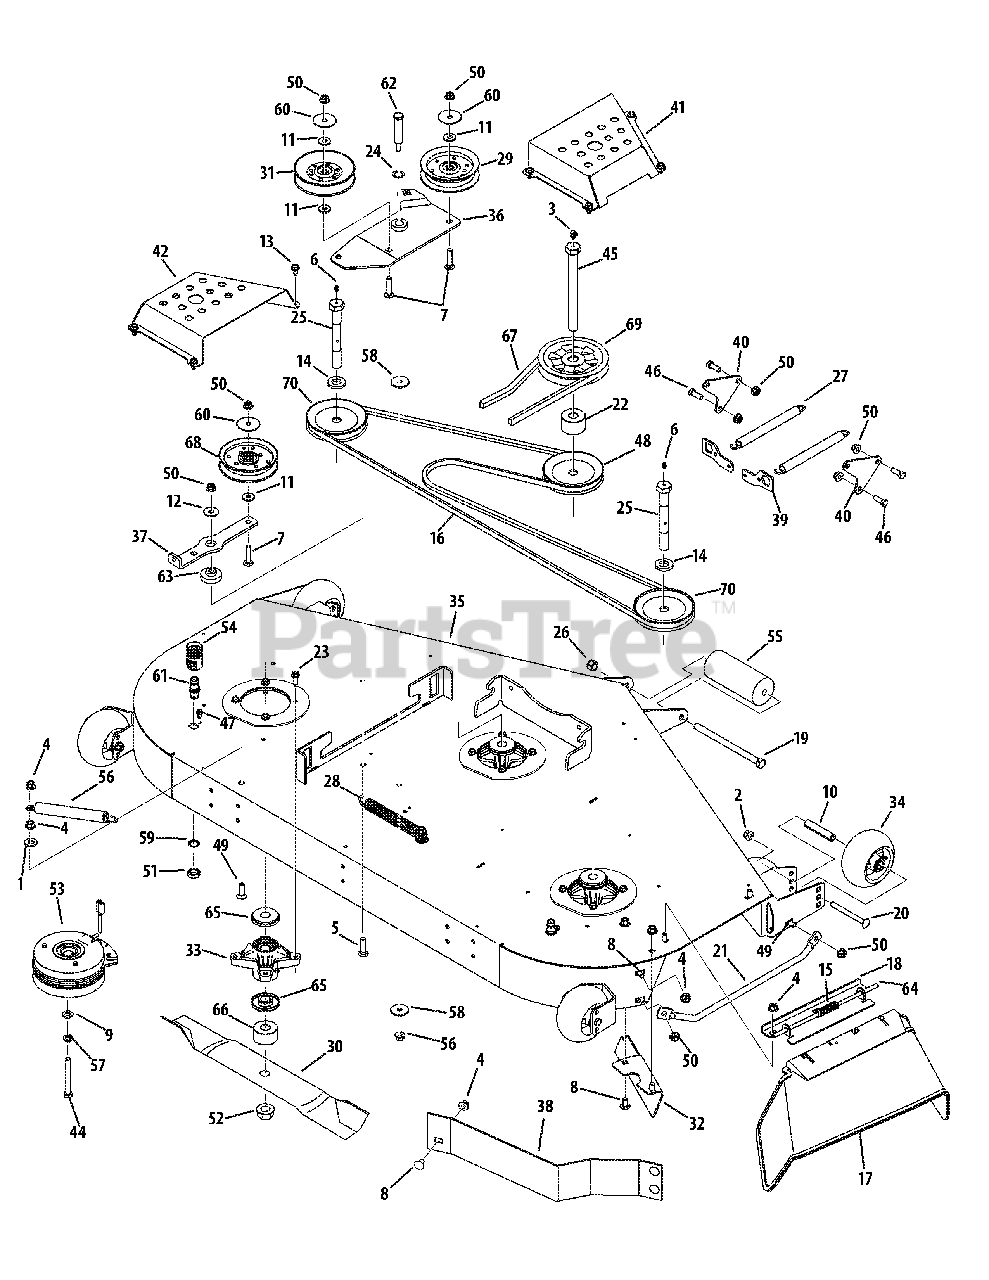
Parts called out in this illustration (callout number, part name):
1	Washer, .532 x 1.06 x .094
2	Hex Screw, 3/8-16 x 4.00
3	Grease Fitting, 1/4-28 x .788
4	Counterlock Flange Nut, 3/8-16
5	Carriage Bolt, 3/8-16 x 1.50
6	Straight Grease Fitting, 1/4-28
7	Carriage Bolt, 3/8-18 x 1.75
8	Carriage Bolt, 3/8-16 x .75
9	Washer, .469 x .875 x .105
10	Spacer, .390 x .620 x 3.04
11	Washer, .406 x 1.00 x .105
12	Washer, .411 x 1.25 x 1.00
13	Flange TT Screw, 5/16-18 x .625
14	Spacer, .812 x 1.47 x .218
15	Torsion Spring
16	V- Belt
17	Fab Deck Deflector Chute
18	Deflector Chute Bracket
19	Hex Screw, 1/2-20 x 7.50
20	Carriage Bolt, 3/8-16 x 4.00
21	Fab Deck Chute Finger Guard
22	Spacer, .760 x 2.00 x 1.28
23	Flange Hex TT Screw, 5/16-18 x 1.00
24	Washer, .625 x 1.00 x .048
25	Hex Screw, 3/4-16 x 6.00
26	Nylock Nut, 1/2-20
27	Hook Ext. Spring, .75 x 7.89 x .14
28	Hook Ext. Spring, .94 x 7.57 x .14
29	Idler Pulley, 4.88
30	Hi-Lift Blade, 21.0
31	Idler Pulley, 5.06
32	Deck Chute Baffle
33	Deck Spindle Assembly
34	Deck Wheel
35	60" Welded Deck
36	60" Idler Assembly
37	Deck Idler Arm
38	Standard Baffle
39	Spring Mount Bracket
40	Spring Mount Plate
41	60" RH Belt Cover
42	60" LH Belt Cover
43	Spindle Reinforcement Plate
44	Hex Screw, 7/16-20 x 3.50
45	Hex Screw, 3/4-16 x 8.0
46	Hex Screw, 3/8-16 x 1.00
47	Hex Washer TT Screw, 1/4-20 x .500
48	Hex Washer TT Screw, 5.16-18 x 1.250
49	Carriage Bolt, 3/8-16 x 1.25
50	Flange Lock Nut, 3/8-16
51	Hex Nut, M16-1.5
52	Flange Lock Nut, 3/4-16
53	Electric PTO Clutch
54	Water Nozzle Adapter
55	Front Roller
56	Extension Spring, .91 x 7.33
57	Lock Washer, 7/16
58	Flat Washer, .390 x 1.500 x .134
59	Lock Washer, 17 x 23.8 x 1.95
60	Flat Washer, .406 x 1.92 x .060
61	Water Deck Nozzle
62	Shoulder Bolt, 3/8-16 x .625 x 2.515
63	Shoulder Spacer, .854 x .280
64	Chute Deflector Rod
65	Deck Spindle Spacer
66	Spindle Spacer, .76 x 2.0 x 1.1
68	Idler Pulley, 4.25
69	V-Type Pulley
70	V-Type Pulley
